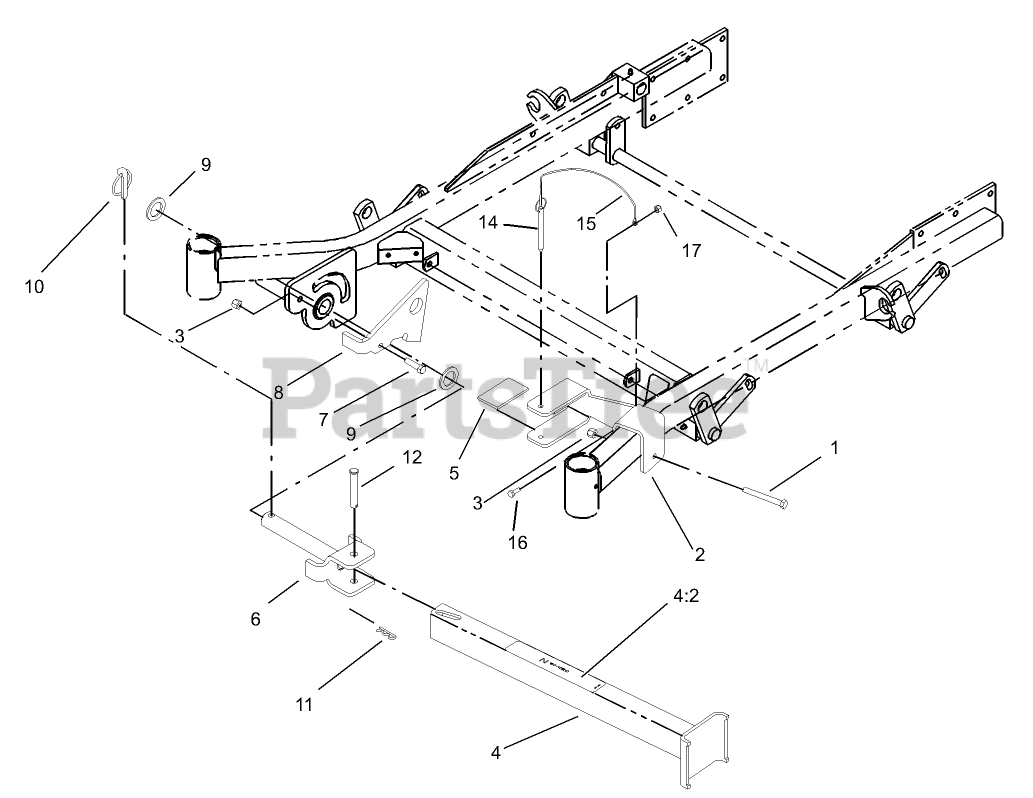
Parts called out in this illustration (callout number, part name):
1	SCREW-HH
2	BRACKET-CRADLE
3	NUT-LOCK, NI
4	Leg ASM
4:2	DECAL-Z STAND
5	PIN-CLEVIS
6	PIN-PIVOT
7	SCREW-HH
8	BRACKET-LATCH
9	WASHER-THRUST
10	PIN-LYNCH
11	PIN-HAIR
12	Cushion-Rubber
14	PIN-HITCH, COTTERLESS
15	LANYARD-NYLON
16	SCREW-HH
17	NUT-LOCK, NI
